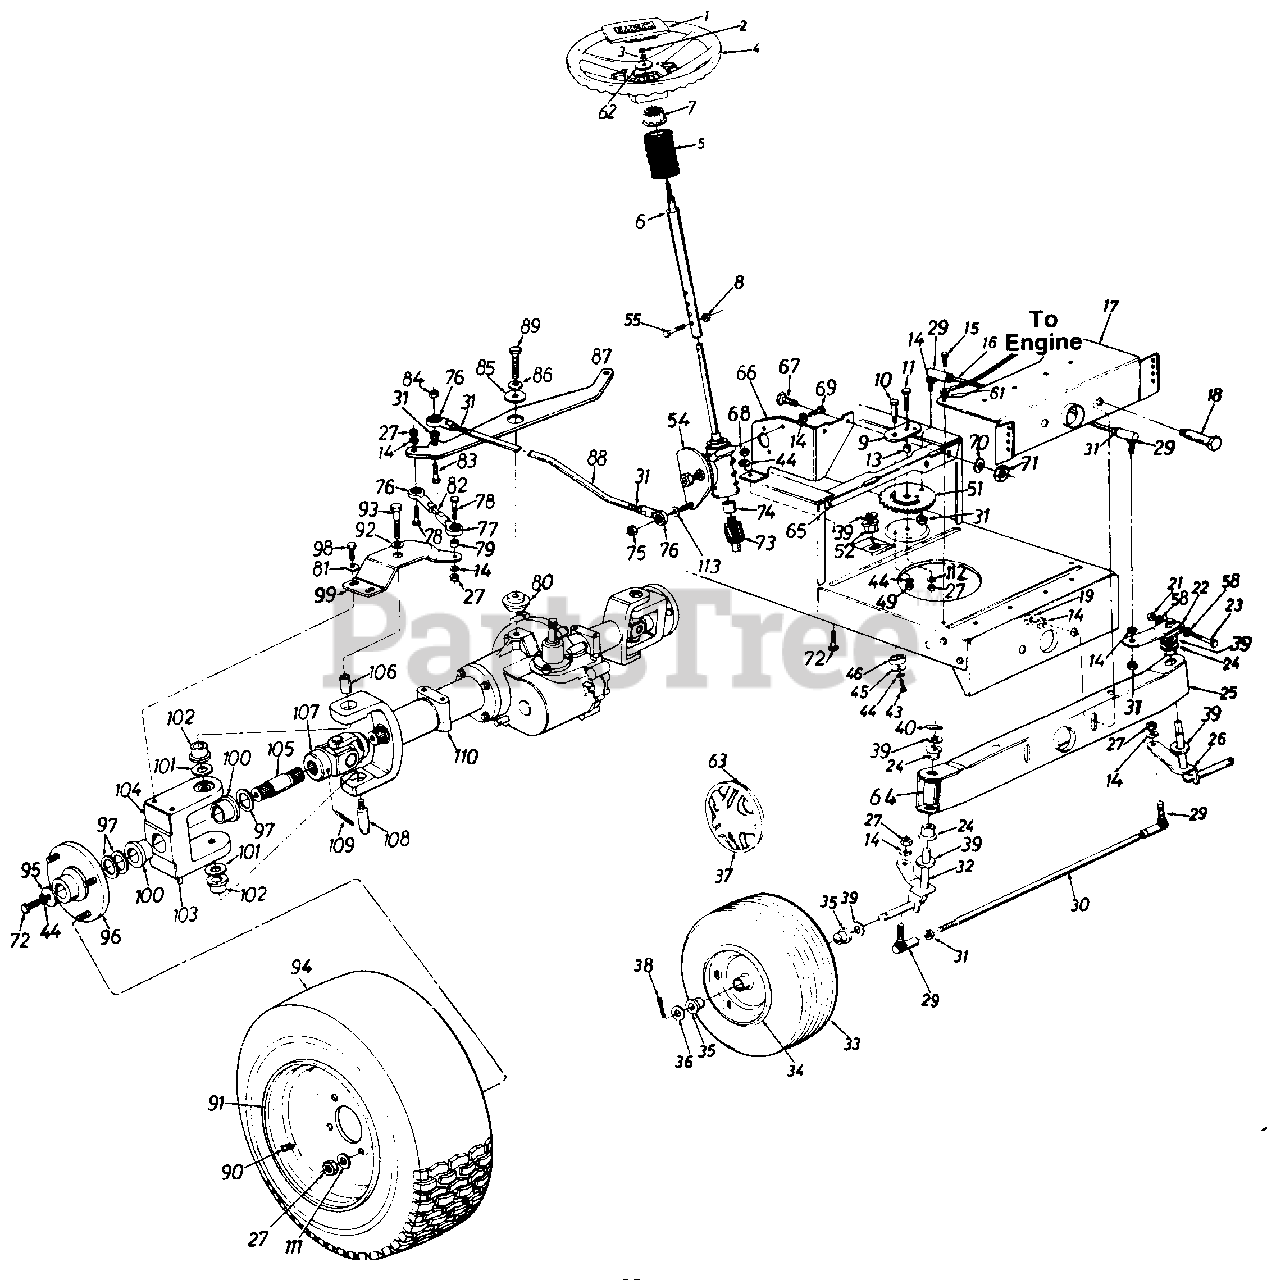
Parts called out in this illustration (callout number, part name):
1	Steering Wheel Insert
2	Hex L-Nut 5/124 Thd.
3	Belleville Wash. .345" l.D.
4	Steering Wheel
5	Steering Bellow
6	Steering Column Ass'y.
7	Steering Wheel Adapter
8	Hex L-Nut 1/4-20 Thd.
9	Retainer Plate
10	Shoulder Bolt .437" Dia. x .35" Lg. 5/16-18 Thd.
11	Hex Bolt 3/8-24 x 1.0" Lg. (Grade 5)
13	Spacer 380" l.D. x.625" O.D. x .227n
14	L-Wash. 3/8" I.D.
15	Hex Wash. Hd. Self-Tap Scr.
16	Steering Drag Link
17	Front Pivot Brkt.
18	Shoulder Bolt .498" Dia. x 2.04" Lg. 3/8-16 Thd.
19	Hex Nut 3/8-16 Thd.
21	Hex Cent. L-Nut 5/16-24 Thd.
22	Steering Arm Front Axle
23	Hex Bolt 5/16-24 x 2.00" Lg. (Grade 5)
24	Hex Flg. Brg. 634" l.D.
26	Front Axle Ass'y.-L.H.
27	Hex Nut 3/8-24 Thd.
29	Ball Joint 3/8-24 Thd.
31	Hex Jam Nut 3/8-24 Thd.
32	Front Axle Ass'y.-R.H.
33	Wheel Ass'y. Comp.734-0864 0 Tire Only
34	Front Wheel Rim Only734-0255 Air Valve 737-0146 Grease Fitting
35	Flange Bearing
36	Fl-Wash. 635" l.D. x 1.59" O.D.
37	Front Hub Cap
38	Cotter Pin 1/8" Dia. x 1.25" Lg.
39	Fl-Wash. 640" l.D. x 24" O.D.
40	Spring Roll Pin
43	Hex L-Bolt 5/16-18 x .62"
44	L-Wash. 5/16" l.D.
45	Fl-Wash. 33" l.D. x 1.25" O.D.
46	Spacer (Plastic)
49	Hex Nut 5/16-18 Thd.
51	Steering Gear Segment
52	Hex Flg. Brg. .634 I.D.
54	Steering Ass'y.
55	Hex Bolt t/4-20 x 1.31" Lg.
58	Wave Wash. .32" I.D. x .62n
61	Ext. L-Wash. 5 6' I.D.
62	Fl-Washer
63	Spring Clip
64	Plastic Tube
65	Horizontal Cross Bracket
66	Vertical Mounting Bracket
67	Hex Bolt 1/4-28 X .75" Lg.
68	Hex Nut 5/16-24 Thd.
69	Hex Bolt 3/8-16 X 1.0' Lg.
70	Bell-Wash. .265' I.D. x .75
71	Hex Nut 1/4-28 Thd.
72	Hex Bolt 5/16-24 X .75 Lg.
73	Pinion Shaft
74	Steering Shaft Splined Coupler
75	Hex L-Nut 3/8-24 Thd.
76	Rod End 3/8-24 Thd.-R.H.
77	Rod End 3/8-24 Thd.-L.H.
78	Hex Bolt 3/8-24 X 1.5" Lg. (Gr. 5)
79	Spacer 38" l.D. x .625n
80	Shld. Spacer 51" l.D.
81	Bell-Wash. 38" l.D. x .88n
83	Hex Bolt 3/8-24 X 1.25" Lg.
84	Hex Patch L-Nut 3/8-24 Tht
85	Fl-Wash. 531" l.D. x 1.75
86	Bell-Wash. 505" l.D. x 1.0"
89	Hex Bolt 1/2-13 X 1.5 Lg. (Gr. 5)
90	Air Valve
93	Hex Bolt 1/2-20 x 2 Lg.
95	Fl-Wash. .33" l.D. x 1.25n
96	Wheel Flange Ass'y.
97	Fl-Wash. 1.0" x 1.56
98	Hex Bolt 3/8-24 X ,75" Lg.
101	Fl-Wash. 76" l.D. x 1.5n
102	Flange Brg. 3/4" l.D.
103	Grease Fitting
104	Wheel Brg. Housing
106	Pivot Sleeve
109	Grooved Roll Pin 1.0" Lg.
110	Axle Horn Ass'y.
111	Bell-Wash. .38" l.D. x .88"
112	Bell-Wash. .39 I.D. x 1.38
113	Fl-Wash. 385" l.D. x .62/
